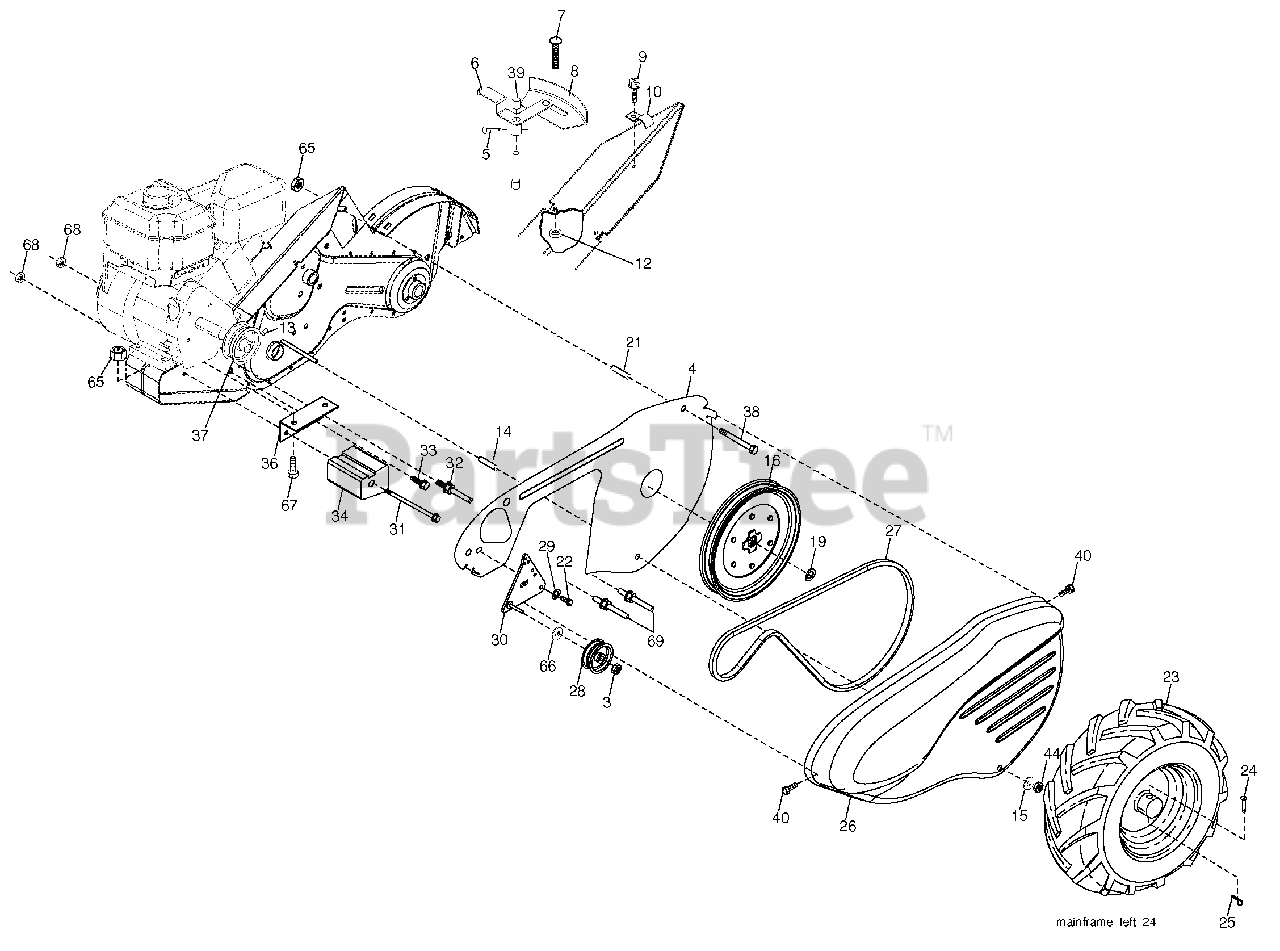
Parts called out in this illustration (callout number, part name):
3	Nut, Hex 3/8-16
4	Shield, Inner Belt Guard RT
5	Screw, Shift Lever
6	Lever, Shift
7	Bolt, Carriage 1/4-20 x 1/2 Gr. 5
8	Plate, Shift Indicator
9	Screw, Hex, Washer Head, Slotted #10-24 x 1/2
10	Clip
12	Nut, Keps Hex 1/4-20 unc
13	Screw, Set, Hex 5/16-18 x 3/8
14	Spacer, Split 0.327 x 0.42 x 1.220
15	Washer 11/32 x 11/16 x 16 Ga.
16	Sheave, Transmission
19	Retainer, Ring
21	Spacer, Split 0.327 x 0.42 x 2.09
22	Bolt, Fin Hex 5/16-24 unf x 1/2
23	Tire
23	Rim
23	Tire Valve
24	Rivet, Drilled
25	Clip, Hairpin
26	Guard, Belt
27	Belt, V
28	Pulley, Idler
29	Ring, Klip
30	Bracket, Idler
31	Bolt, Hex 5/16-16 x 12
32	Shaft, Idler Arm
33	Bolt, Hex 3/8-16 x 1
34	Counterweight, L. H.
35	Bolt, Hex 5/16-18 x 1-3/4
36	Bracket, Reinforcement, L. H.
37	Sheave, Engine
38	Bolt, Fin Hex 5/16-18 unc x 2-3/4
39	Cap, Plunger Blk
40	Screw Hex Wsh Slt #10-24 x 1/2
44	Nut Lock Hex w/Ins 5/16-18 unc PL
65	Nut Lock Hex Flange
66	Washer 13/32 x 13/16 x 12 Ga.
68	Nut Keps Hex 3/8-16 unc
69	Keeper Belt Engine
